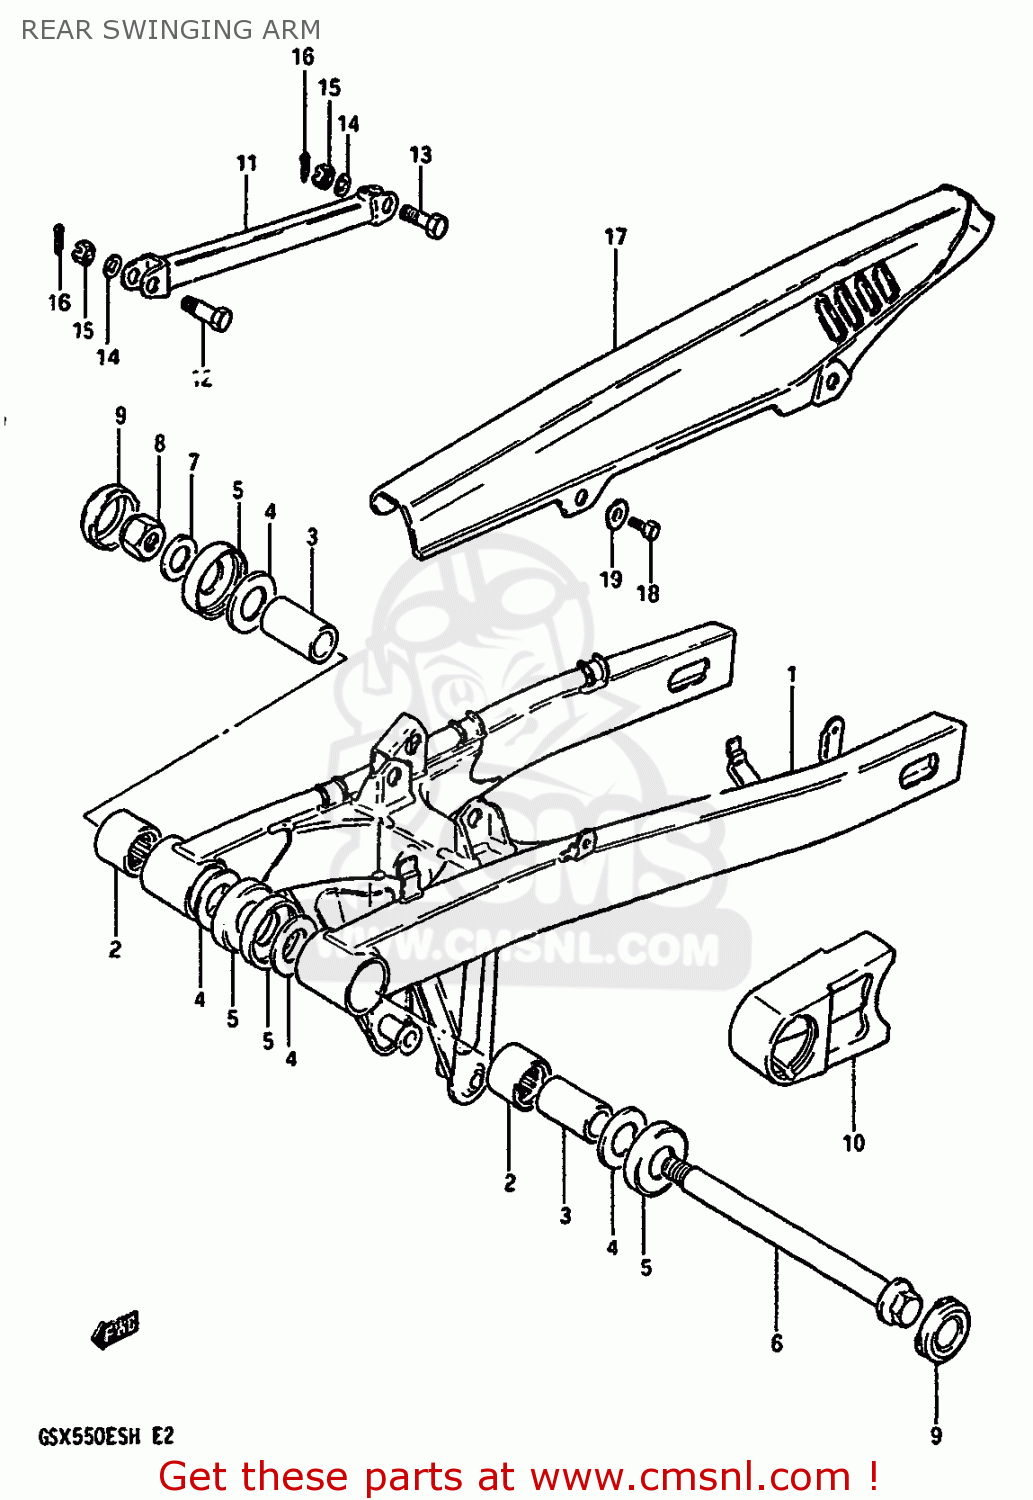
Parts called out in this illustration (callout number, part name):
1	ARM,REAR SWING
2	BEARING(25X33X30)
3	SPACER,RR SWGARM PIVOT
4	WASHER
5	COVER,RR SWGARM DUST SEAL
6	SHAFT,REAR SWING ARM
7	WASHER
8	NUT
9	CAP,SWINGINGARM PIVOT
10	BUFFER,DEFENSE
11	TORQUE LINK,REAR
12	BOLT
13	BOLT
14	WASHER 10MM
15	NUT
16	PIN 20X20
17	CASE,CHAIN
18	BOLT
19	WASHER
